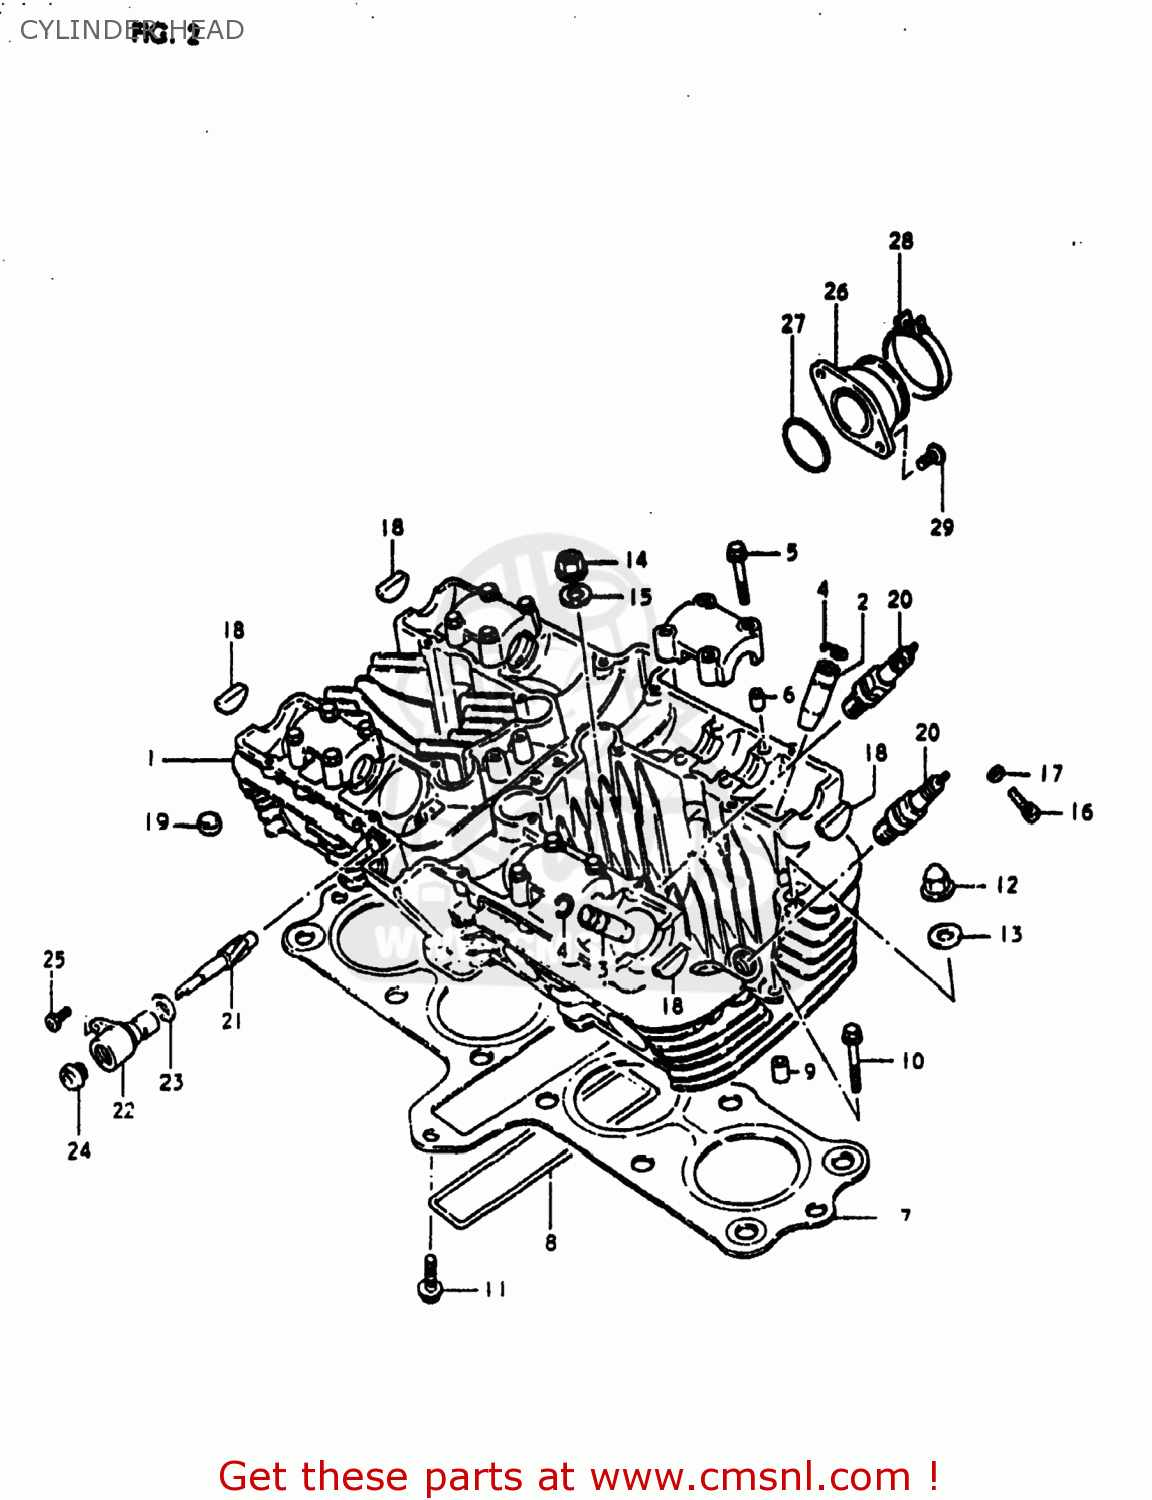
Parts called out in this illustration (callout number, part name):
1	HEAD ASSEMBLY,CYLINDER
2	GUIDE,INTAKE VALVE
3	GUIDE,EXHAUST VALVE
4	RING,SNAP
5	BOLT(6X39)
6	PIN(6.2X8X11)
7	GASKET,CYLINDER HEAD (MCA)
8	O RING(D:3,ID:26X157)
9	PIN
10	BOLT,UNDER
11	BOLT
12	NUT
13	GASKET(10.5X22X2) (NAS)
14	NUT
15	WASHER(10.5X22X2.3)
16	BOLT
17	GASKET(5.3X9.3X1.2) (NAS)
18	PLUG
19	PAD
20	SPARK PLUG
21	GEAR,TACHOMETER DRIVEN
22	SLEEVE,TACHOMETER DRIVE GEAR
23	SEAL,TACHOMETER DRIVEN
24	SEAL,OIL(5X12X8)
25	SCREW(5X12)
26	PIPE,INTAKE
27	O-RING (D:2.4 ID:39.7)
28	CLAMP
29	SCREW
